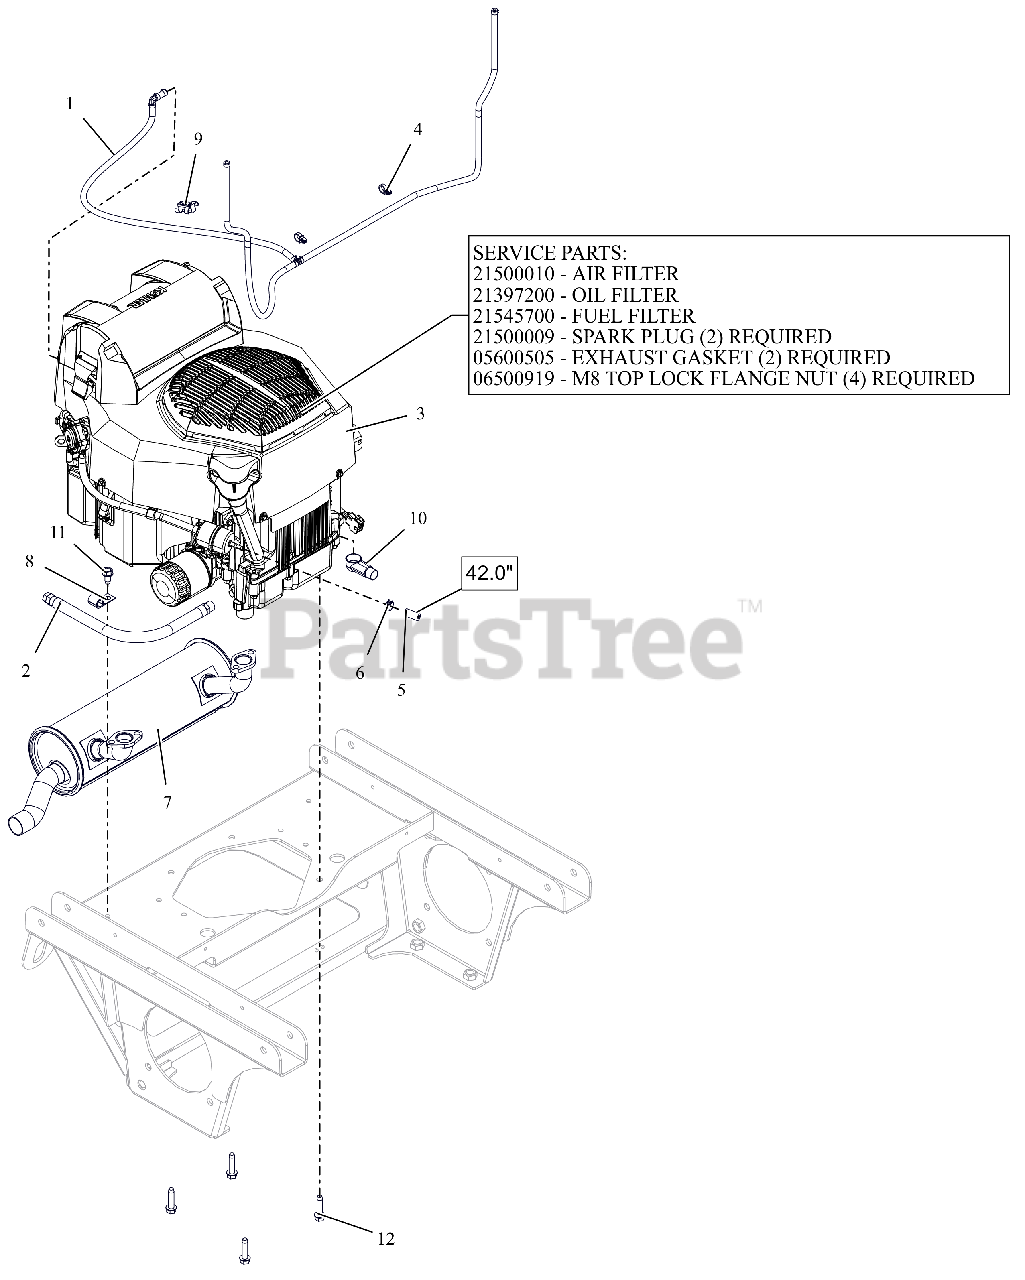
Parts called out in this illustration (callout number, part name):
1	ASM, VAPOR LINE
2	HOSE, OIL DRAIN
3	ENGINE, KOHLER ZT740 CONFIDANT
3	AIR CLEANER, KOHLER CONFIDANT
3	FILTER, OIL - KOH CV20
3	FILTER-FUEL KOHLER COURAGE PRO
3	PLUG, SPARK KOHLER
3	GASKET, MUFFLER KOHLER TWIN
3	NUT-LK-TOP-FLG M8 ZCC
4	ROUTING CLIP (1/2" ID)
5	HOSE, .25 LOW-PERM BULK GAS
6	CLAMP, FUEL LINE
7	MUFFLER, ZT730/ZT740
9	CLIP, T, .38-.50
10	BOOT, .65ID POS
11	SCR,TAP .375-16X.75 HWH TR ZCC
12	SCR-TAP .38-16X1.50 HWH ZCC
